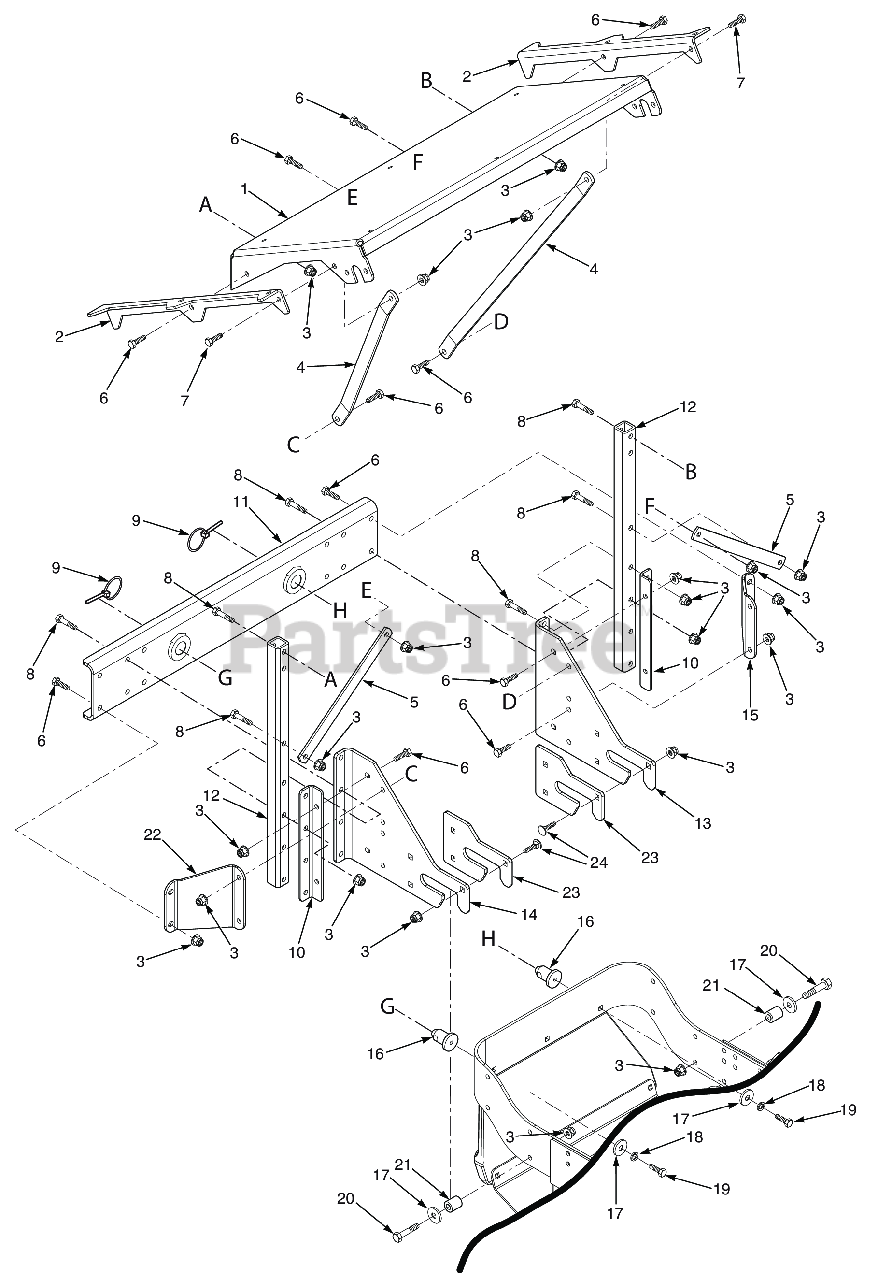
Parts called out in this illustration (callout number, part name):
1	Support Frame, Hopper
2	Bracket, Hopper Support
3	Nut, Flange Elastic Stop Nut, 3/8-16
4	Brace, Stiffener
5	Brace, Engine Mounting
6	Bolt, Hex Head, 3/8-16 x 1 Gr. 5
7	Bolt, Hex Head 3/8-16 x 1-1/4", Kawasaki FX / FS
8	Bolt, Hex Head 3/8-16 x 2-1/4" - 61"
9	Quick Pin, 5/16" Dia.
10	Mounting Bracket, Tube
11	Mounting Bracket Weldment
12	Tube, Upright
13	Mounting Bracket, GC R.H.
14	Mounting Bracket, GC L.H.
15	Angle Bracket, GC
16	Pin, GC Locator
17	Flatwasher, 3/8-.406 x 1-1-1/2 x 7 Gauge
18	Lockwasher, 3/8" Spring, Kawasaki FX / FS
19	Bolt, Hex Head 3/8-16 x 1-1/4", Kawasaki FX / FS
20	Bolt, Hex Head 3/8-16 x 2-1/4" - 61"
21	Spacer
22	Angle Bracket, GC
23	Wear Plate, GC
24	Carriage Bolt, 3/8-16 x 1-1/4"
